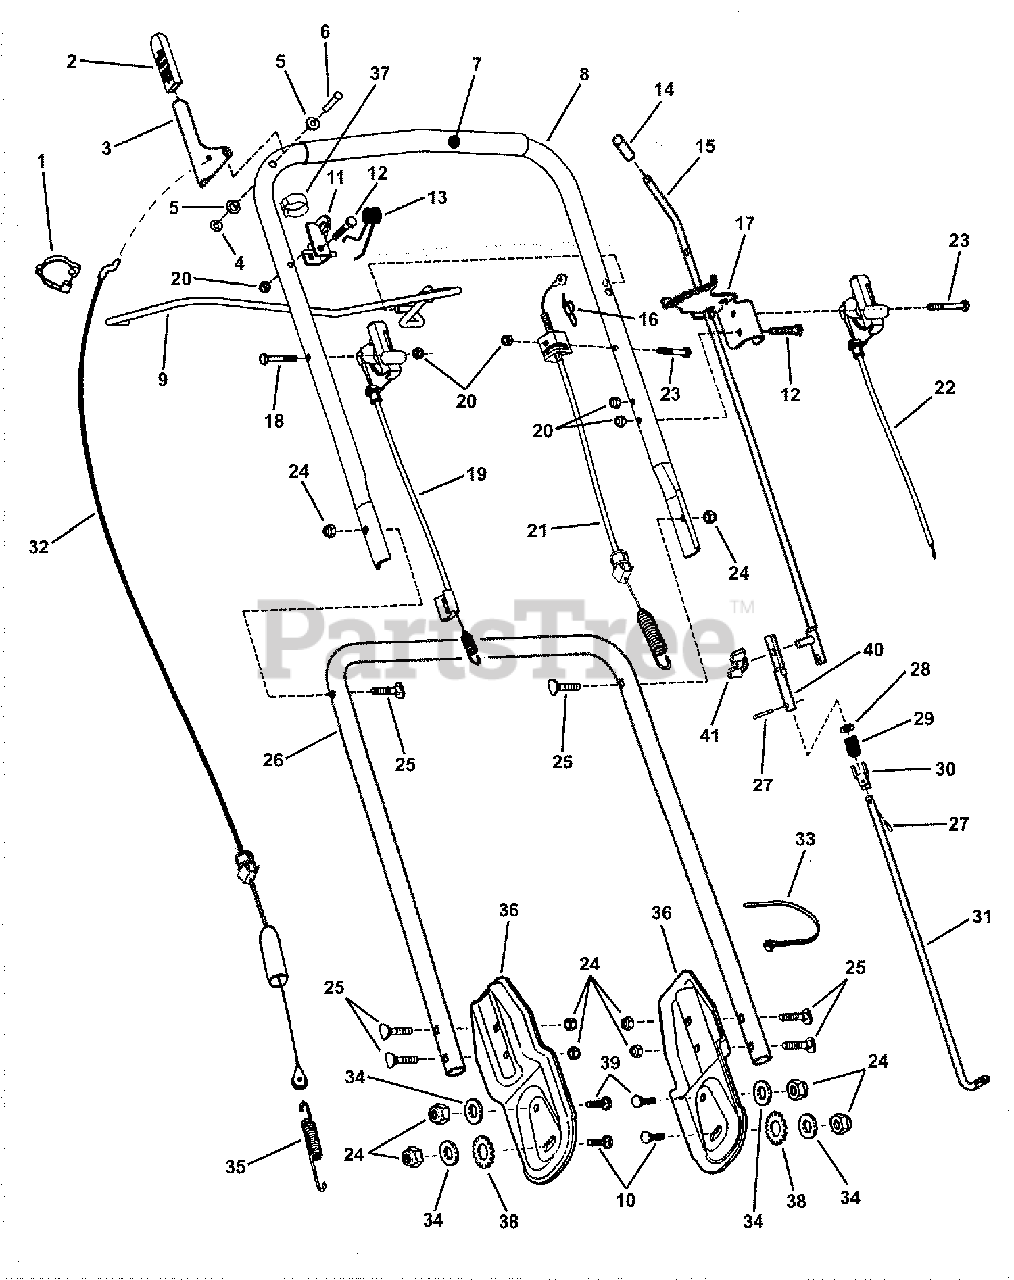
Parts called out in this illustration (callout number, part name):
1	CLAMP, 7/8" Double Cable
2	GRIP, Wheel Drive Handle
3	HANDLE, Wheel Drive
4	PUSHNUT, 1/4"
5	BUSHING, Flange
6	PIN, 1/4 x 1-1/2"
7	FOAM GRIP, Handle
8	HANDLEBAR, Upper
9	CONTROL, Blade
10	BOLT, 5/16-1/ x 1" Square Neck Carriage GR5
11	WELDMENT, Blade Brake Control Bracket
12	SCREW, 1/4-20 x 1-1/2" Hex Head Cap GR5
13	SPRING - Blade Control
14	GRIP, Vinyl
15	ROD, Upper Shift
16	PIN, 5/16" Self Lock Cotter
17	SECTOR, Speed
18	SCREW, 1/4-20 x 1-3/4" Hex Head Cap GR5
19	CABLE, Swivel Wheel Latch
20	NUT, 1/4-20 Hex Nyloc
21	CABLE, BBC Control
22	CONTROL, Throttle
23	SCREW, 1/4-20 x 2" Hex Head Cap GR5
24	NUT, 5/16-18 Hex Lock
25	BOLT, 5/16-18 x 1-1/2" Curved Head Carriage
26	HANDLEBAR, Lower
27	PIN, 1/8" x 1" Roll
28	WASHER, 11/32" Flat
29	SPRING, Compression, Shift Rod
30	CONNECTOR, Shift Rod
31	ROD, Lower Shift
32	CABLE, Clutch Pull, Z-Bend
33	TIE, Wire
34	WASHER, 11/32" Flat
35	SPRING, Clutch
36	BRACKET, Lower Handle
37	CLIP, Wiring Harness
38	WASHER, 5/16" Internal/External Tooth Lock
39	BOLT, 5/16-18 x 3/4" Short Neck Carriage GR5
40	ROD, Middle Shift
41	NUT, 1/4-20 Wing Nyloc
